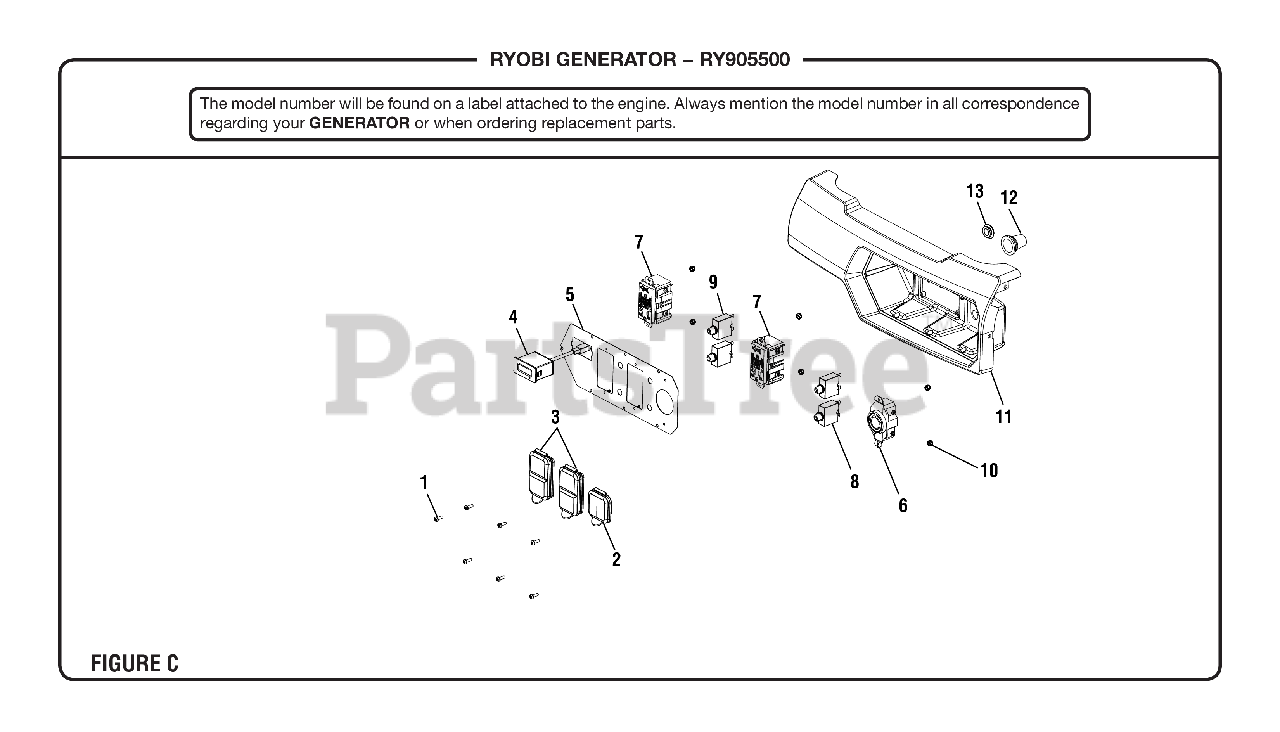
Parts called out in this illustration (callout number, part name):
1	Screw (#8-18 x 1/2 in., T20 Torx Pan Hd.)
2	240 Volt ReceptacleRain Cover
3	120 Volt Receptacle Rain Cover
4	Digital Display
5	Front Panel
6	Twist Lock Recepticle (120/240 Volt, 30 Amp, L14-30)
7	Duplex Receptacle (120 Volt)
8	Circuit Breaker (25 Amp)
9	Circuit Breaker (20 Amp, 125 Volt)
10	Lock Nut (M4)
11	Control Box (Back Panel)
12	Wiring Rubber Boot
